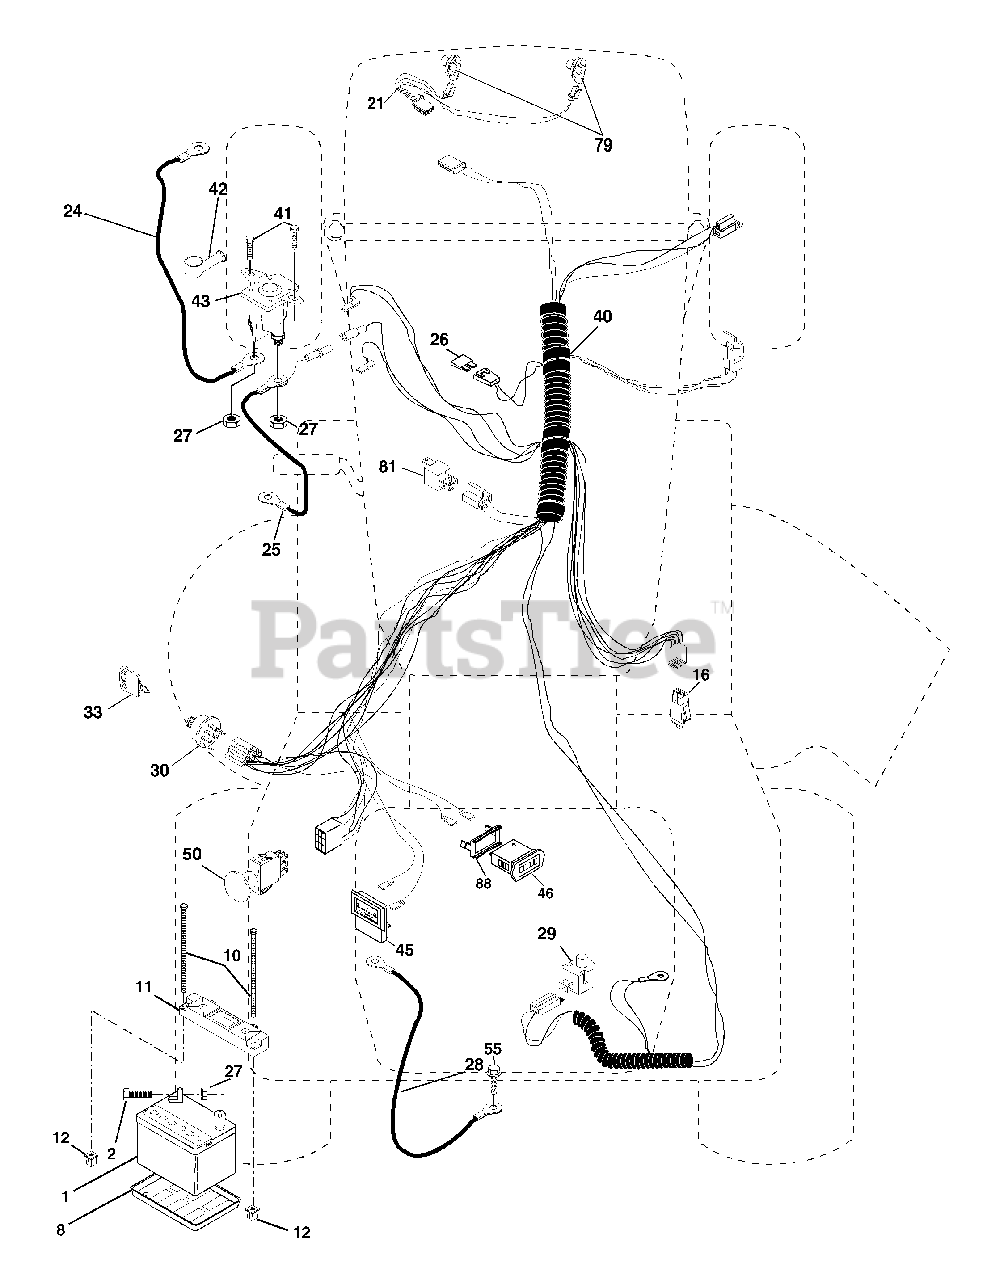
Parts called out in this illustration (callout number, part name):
1	Battery
2	Bolt Hex Hd 1/4-20 UNC X 3/4
8	Tray, Battery
10	Bolt, BTR FRT 1/4-20 x 7.5
11	Hold Down Battery, Front
12	Nut, Push, Nylon
16	Switch Interlock Push-In
21	Harness Asm Light W/Bulbs
24	Cable Battery
25	Cable Batterywire
26	Fuse
27	Nut Keps Hex 1/4-20 Unc
28	Cable Ground
29	Switch Plunger Normal OP Olive
30	Switch Ign 4 pos w/lights
33	Key Ign
40	Harness Ign.
41	Bolt Blk Fin Hex 1/4-20 x 1/2
42	Cover Terminal Red
43	Solenoid
45	Ammeter Rectangular
46	Hourmeter Snap-In
50	Switch, PTO
55	Screw Thdrol 5/16-18 x 1/2
79	Bulbholder
81	Relay Asm
89	Bracket Snap-In Hourmeter
